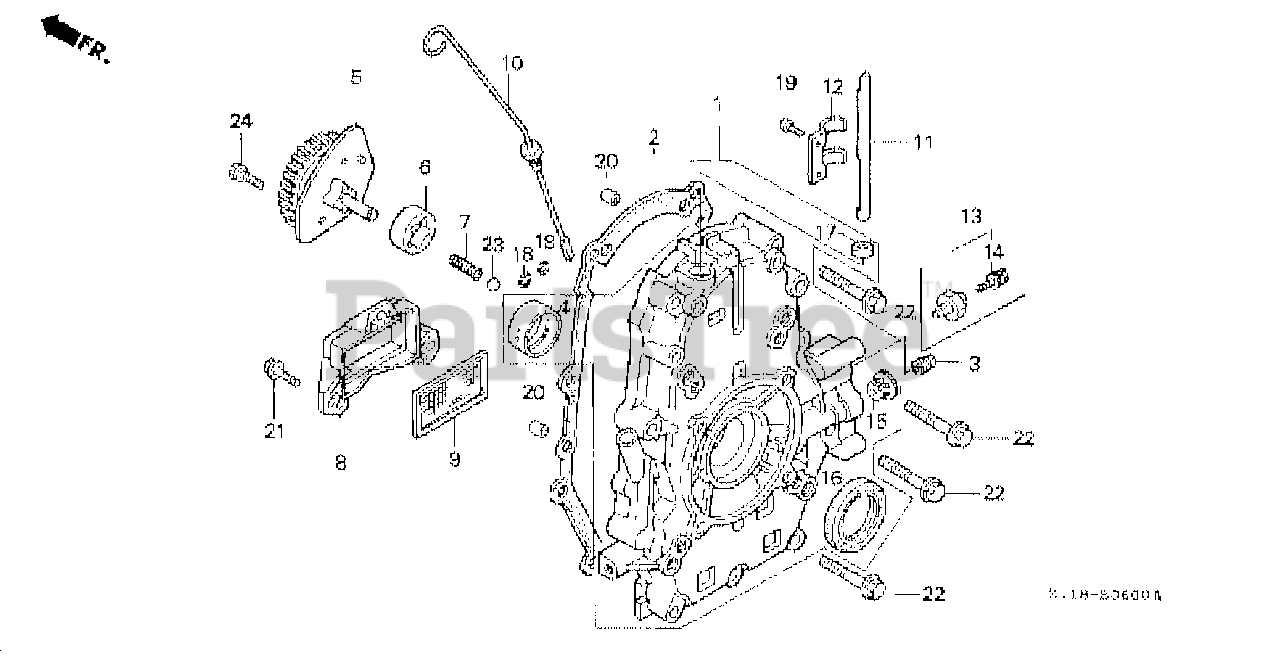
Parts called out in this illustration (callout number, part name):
1	COVER ASSY., CRANKCASE
2	GASKET, CASE COVER
4	BEARING A, MAIN (TO SELECT CORRECT BEARING,
4	BEARING B, MAIN (TO SELECT CORRECT BEARING,
4	BEARING C, MAIN (TO SELECT CORRECT BEARING,
5	COVER ASSY., OIL PUMP
6	ROTOR, OIL PUMP (OUTER)
7	SPRING, RELIEF VALVE
8	COVER, OIL FILTER
9	SCREEN, OIL FILTER
10	DIPSTICK, OIL
11	SHAFT, GOVERNOR ARM
12	FORK, GOVERNOR
13	SWITCH, OIL PRESSURE
14	SCREW-WASHER (4X8)
15	BOLT, SEALING
16	OIL SEAL (38X58X11)
17	OIL SEAL (10X16X4.5)
18	O-RING (13X3.0)
19	SCREW, PAN (5X10)
20	PIN A, DOWEL (8X14)
21	BOLT, FLANGE (6X20)
22	BOLT, FLANGE (8X50)
23	BALL, STEEL (#12) (3/8)
24	BOLT, SOCKET (6X16)
